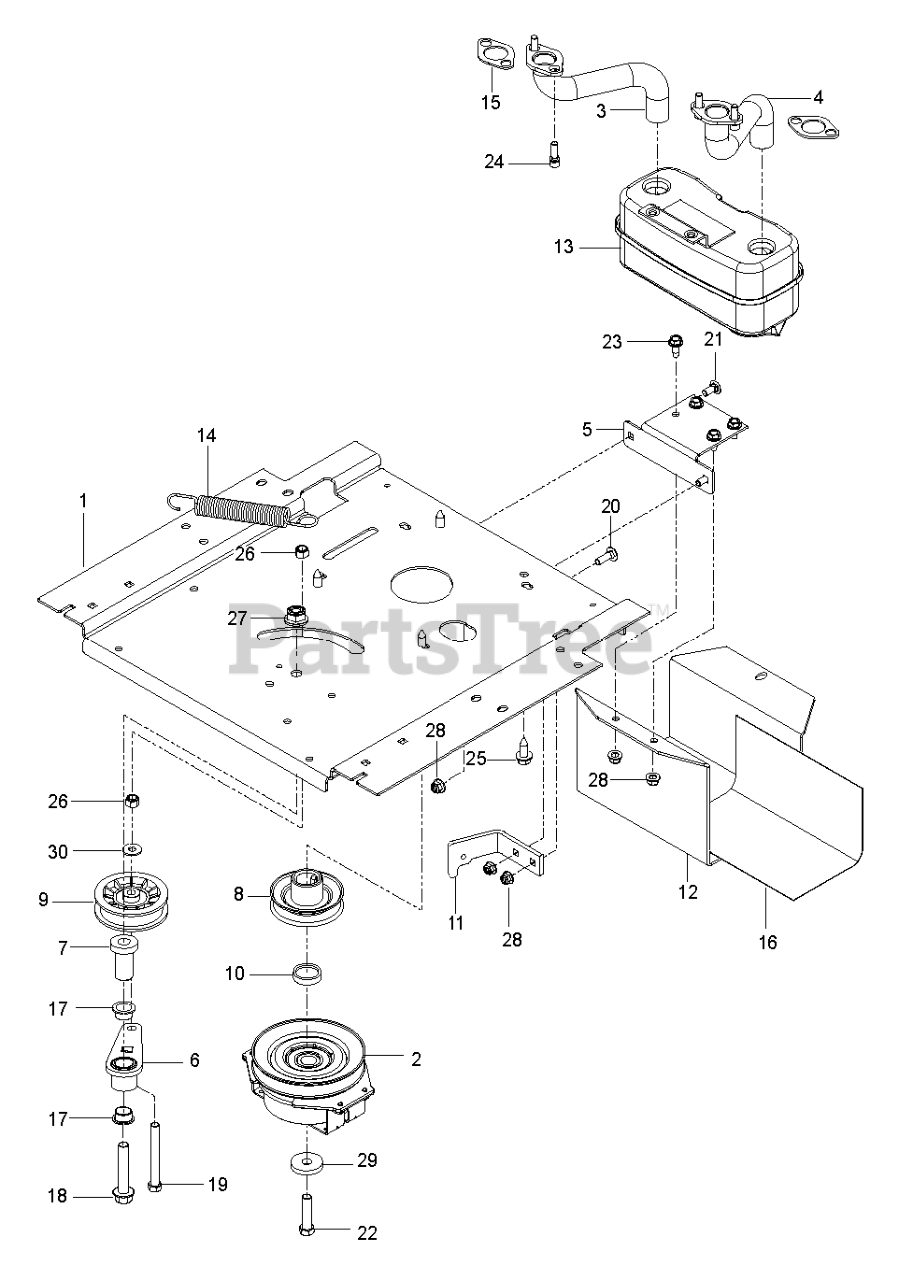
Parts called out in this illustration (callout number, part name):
1	PLATE.ENGINE.PNT.23"FRAME.EDIP
2	CLUTCH.OGURA.5.0PD.GT1.5A-EH07
3	EXHAUST.TUBE.LH.BS/TWIN
4	EXHAUST.TUBE.RH.B&S.TWIN.INTEK
5	BRACKET MUFFLER MS431BLK
6	ARM IDLER
7	SPINDLE.IDLER
8	PULLEY.ENGINE
9	PULLEY, IDLER RAKE & ZTR
10	SPACER.SPACER.625 W/OGURA.LCC
11	CLUTCH.STOP.OGURA LCC.BLACK
12	GUARD.MUFFLER.WO.TOW.HITCHX431
13	MUFFLER ASM TWIN
14	SPRING, DECK DRIVE
15	GASKET.MUFFLER
16	HEAT SHIELD
17	BEARING.FLANGED.PLASTIC.3/4ID
18	BOLT.FLANGE.1/2-13 X 2.75.GRD5
19	HCS 3/8-16X3-1/2 TAPBLT GR5 ZD
21	RP BOLT 5/16-18 X3/4 ZN/YEL GR
22	CLUTCH BOLT7/16-20X2.5 GR524HR
23	SCREW.THDROL.5/16-18X3/4.TTY
24	SCREW.SOCKET.HEAD.5/16-18
25	NUT 3/8-16 NYLOC
26	NUT, 1/2-13 HEX FLG NYLOC ZD
27	5/16-18 NYLOC FLANGE NUT
28	NUT 3/8-16 NYLOC
30	WASHER 5/16 FLAT
